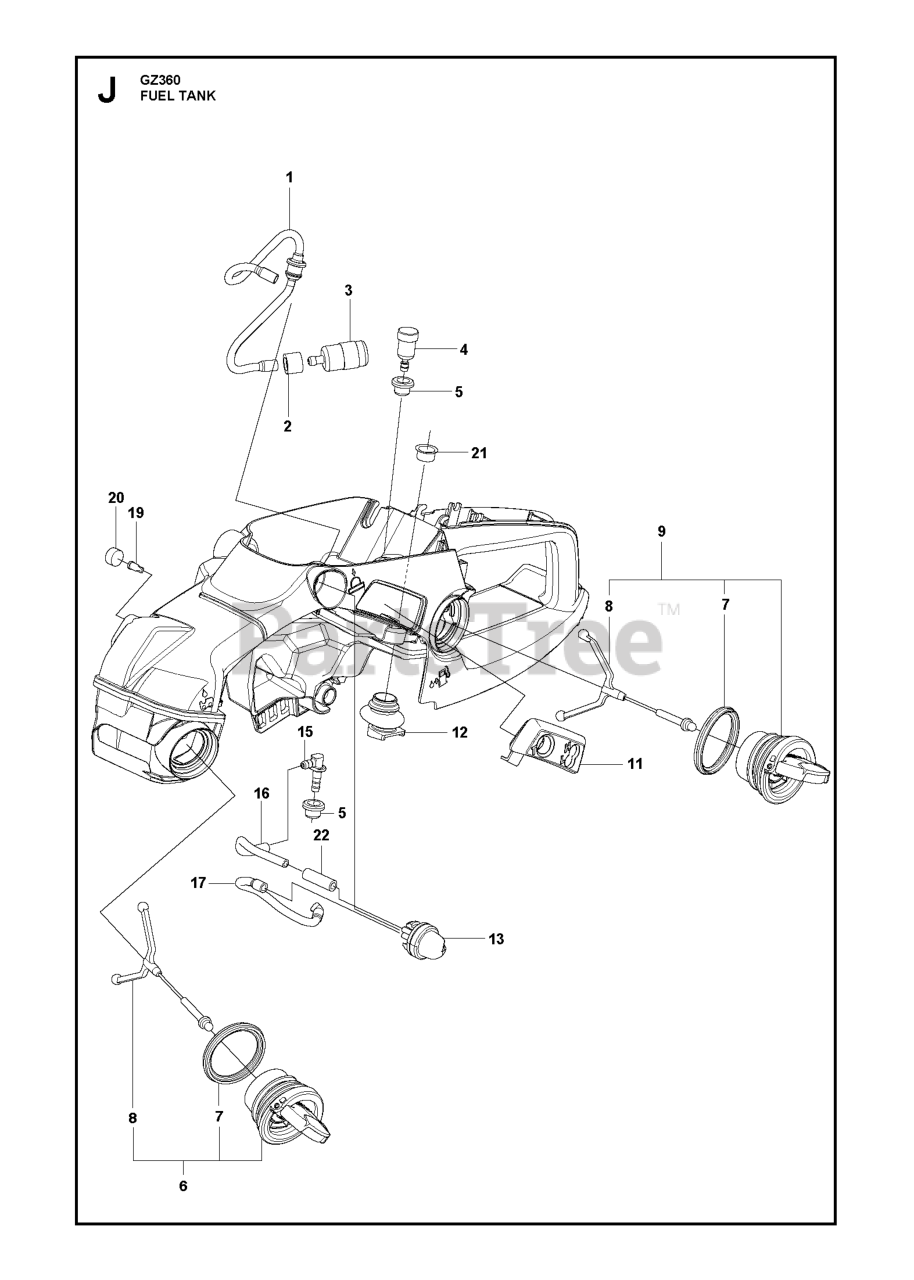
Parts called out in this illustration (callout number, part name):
1	FUEL HOSE ASSY 439
4	BREATHER
5	GROMMET
6	TANK CAP ASSY
7	GASKET TANK CAP
8	TANK LOCK
9	TANK CAP ASSY BLACK, NEW GASK
11	GROMMET CARB 439
12	PIPE, AIR
13	PRIMARY BTN
15	ELBOW
16	FUEL HOSE L90
17	PIPE 8488G11150
19	AIR CONTROL BREATHER
20	BREATHER SEAL
